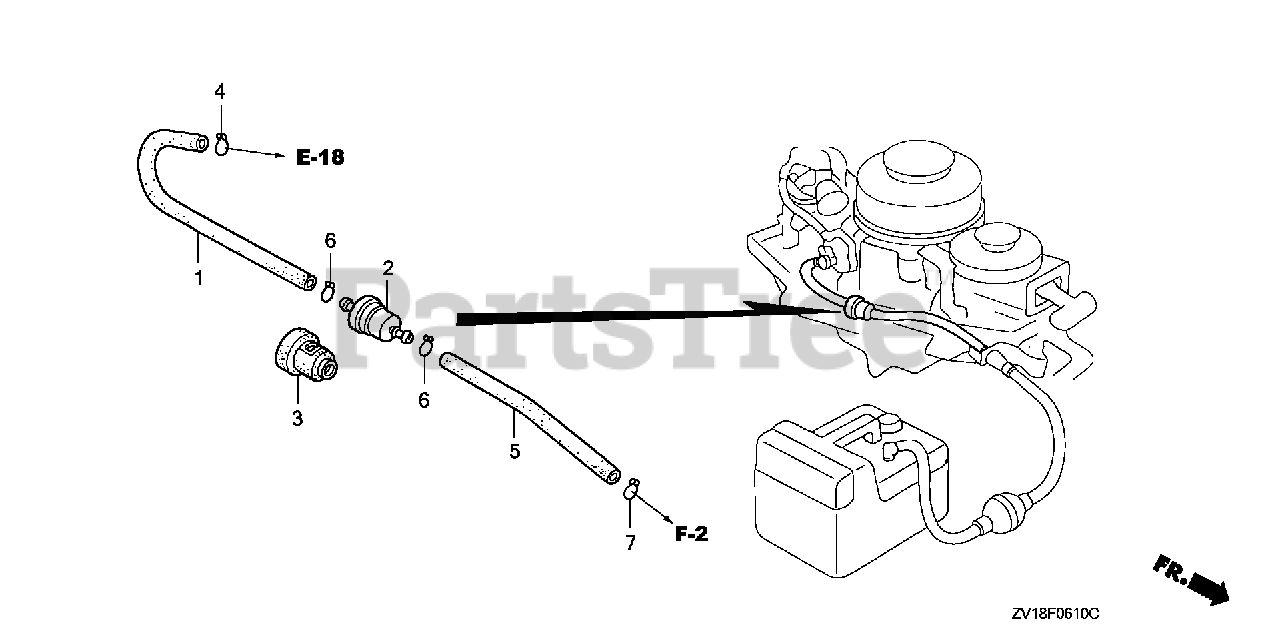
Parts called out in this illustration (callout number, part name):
1	TUBE, FUEL (4.5MM) (ENGINE NO.)
2	STRAINER, FUEL
3	SUSPENSION, STRAINER
4	CLIP, TUBE (B8)
5	BULK HOSE, FUEL (4.5X3000) (4.5X265)
5	BULK HOSE, FUEL (4.5X3000) (4.5X270) (ENGINE NO.)
6	CLIP, TUBE (B8)
7	CLIP, TUBE (B8)
